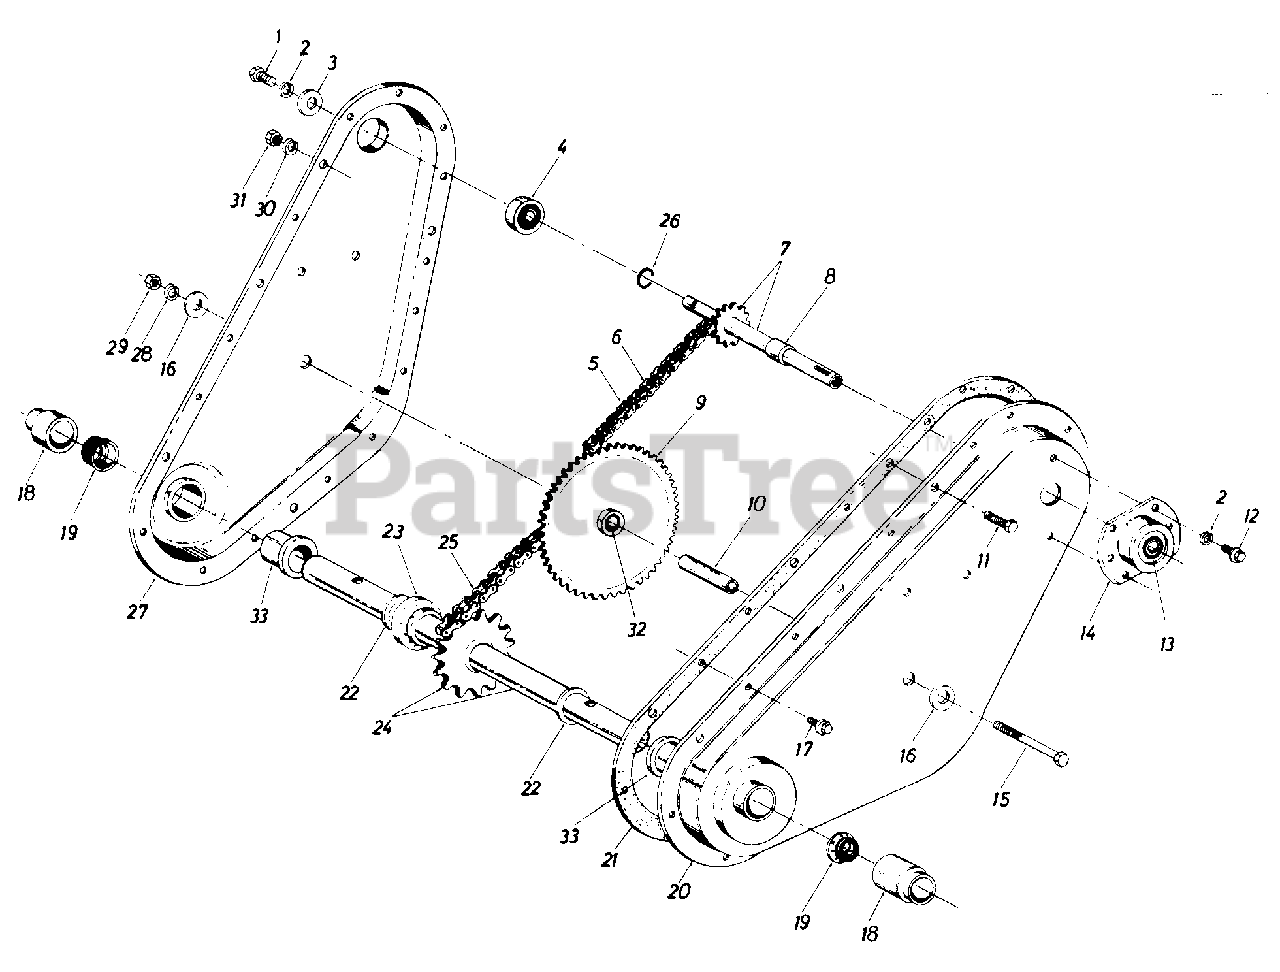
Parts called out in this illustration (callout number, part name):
1	Hex L-Scr. 1/4-28 x .625" Lg.
2	L-Wash. 1/4" I.D.*
3	Fl-Wash. .25" I.D. x .93" O.D. x .125" Thk.
4	Bearing .62" I.D. x 1.38" O.D. x .437" Thk.
5	#35 Chain 3/8" Pitch x 52 0 Links-Endless
6	Master Link
7	Input Shaft Assembly
8	Spacer
9	Sprocket Assembly
10	Sprocket Hub Tubing 3/8" I.D. x 5/8" O.D. x 1.9" Lg.
11	Hex Scr. 5/16-18 x .625" Lg.
12	Hex Wash. Hd. Self-Tap Scr. 1/4-20 x .50" Lg.
13	Bearing .625" I.D. x 1.38" O.D. x .437" Thk.
14	Bearing Housing
15	Hex Scr. 3/8-24 x 2.75" Lg.
16	Fl-Wash. 3/8" I.D. x 1.25" O.D. x .100 Thk.
17	Hex Wash. Hd. Self-Tap Scr. 1/4-20 x .50" Lg.
18	Dust Cap
22	Thrust Wash. 1.00" I.D. x .030" Thk.
23	Step Spacer
24	Tine Shaft Assembly
25	#50 Chain 5/8" Pitch x 46 0 Links-Endless
26	Snap Ring
29	Hex Nut 3/8-24 Thd.
30	L-Wash. 5/16" Scr.
31	Hex Nut 5/16-18 Thd.*
32	Bearing
33	Bearing
14984-0638	HOUSING ASSEMBLY RH BLACK - MTD/TROY-BILT RED (0638)
